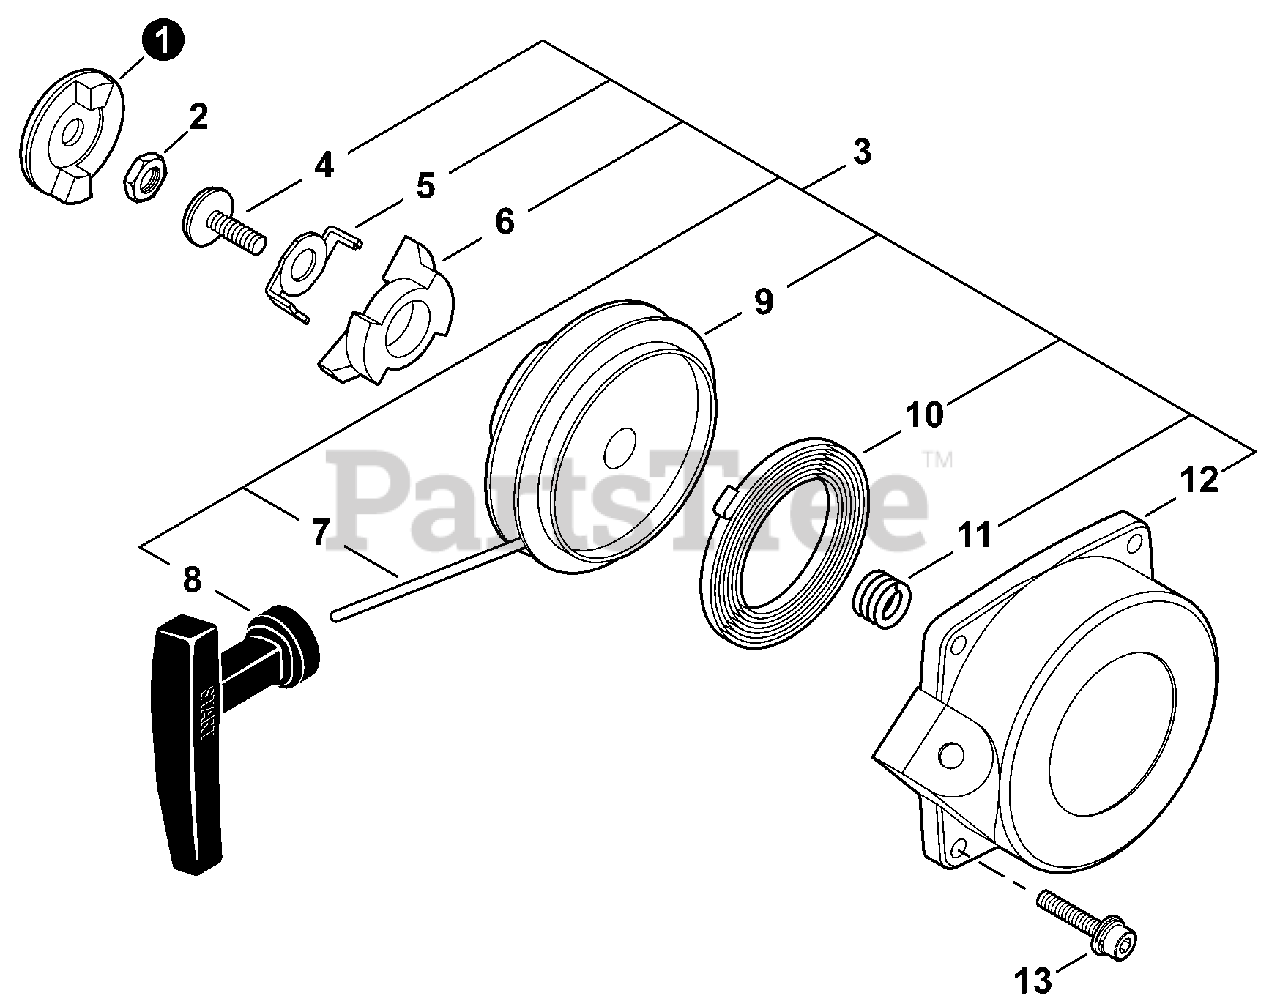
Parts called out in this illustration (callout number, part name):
1	PULLEY, STARTER
2	NUT M8×1
3	STARTER ASSY, RECOIL
5	RETAINER
6	PAWL, STARTER
7	ROPE, STARTER
8	GRIP, STARTER
9	REEL, ROPE
10	SPRING, RECOIL
11	SPRING, PAWL
12	CASE, RECOIL STARTER
13	BOLT 5×20
